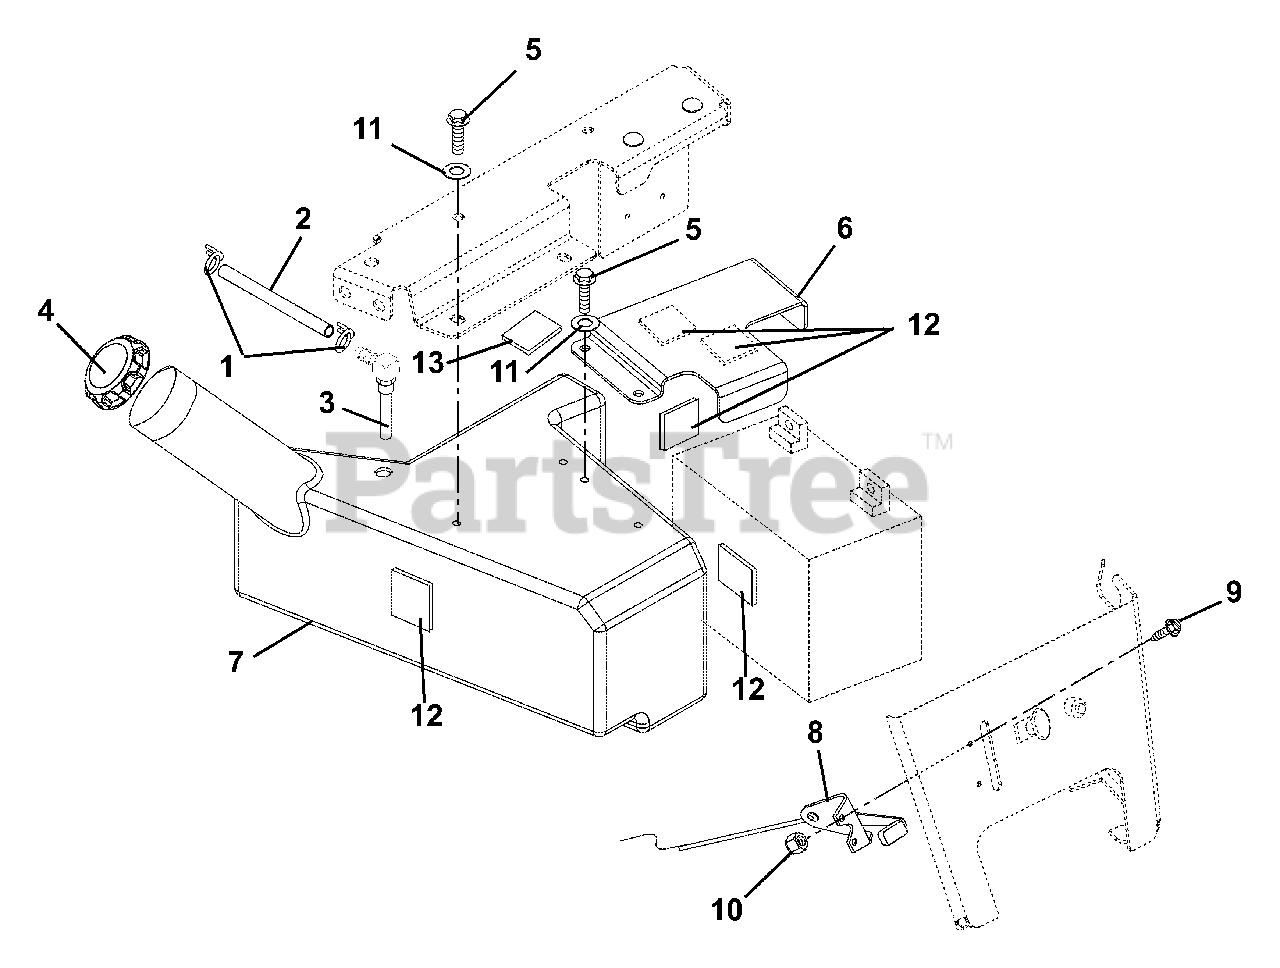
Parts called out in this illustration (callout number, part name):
1	Clamp, Hose Wire .490 /.510 x .116
2	Gas Line, Bulk 1/4" I.D.
3	Fitting, Tank
4	Fuel Cap
5	Bolt, Serrated Hex Flange Washer Head .25-20 x .75
6	Bracket, Battery
7	Tank, Fuel
8	Cable, Throttle
9	Screw, Machine 10-24 x .50 Hex Washer Head
10	Nut, Locking Nylon 10-24 with Insertg
11	Washer-Locking .31 x .078 Regular
12	Pad, Foam
13	VHB Tape
